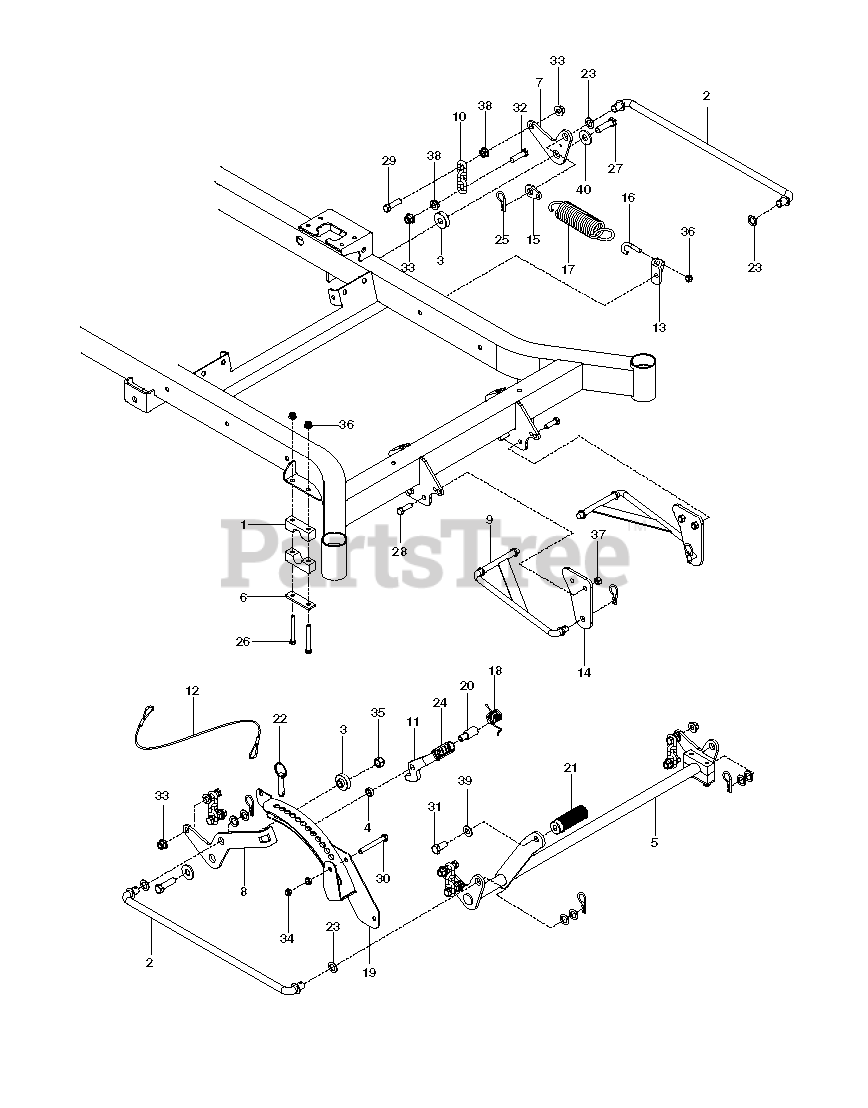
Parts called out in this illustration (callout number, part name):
1	PILLOW BLOCK
2	CROSS LINK
3	IDLER SPACER
4	SPACER, .3
5	SHAFT FRONT LIFT BLK
6	REINFORCEMENT BAR
7	BELLCRANK, RR, LIFT
8	BELLCRANK, RR, RT
9	STRUT LINKAGE
10	LIFT CHAIN - 3 LINK
11	LATCH, TRANSPORT
13	MOUNT, SPRING
14	MOUNT, STRUT
15	TAB, SPRING
16	J-BOLT
18	SPRING, TORSION
19	HEIGHT, ADJUST, DECK
20	PIVOT, LATCH, TRANSPORT
21	PEDAL, DECK HEIGHT
22	PIN, 1/2 X 1 1/2, DETENT RING
23	BUSHING
24	GRIP, TRANSPORT-RELEASE
25	PIN, COTTER 1 3/4
26	HCS 5/16C X 2-3/4
27	HCS 1/2-13 X 1 3/4 GR 8
28	HCS 3/8C X 1 1/4 GR5
29	HCS 7/16C X 1 1/2
30	HCS 3/8C X 3
31	HHCS 1/2-13 X 1
32	HCS 7/16 - 14 X 1 3/4
33	NUT 7/16-14 HEX WHIZ LK
34	NUT HEX 3/8-16 NYLON, THIN
35	NUT 1/2-13 HEX NYLOC ZD
36	5/16-18 NYLOC FLANGE NUT
37	NUT 3/8-16 NYLOC
38	NUT 7/16C WHIZ
39	WASHER, 7/16 DISC SPRING
40	WASH USS FLAT 1/2
